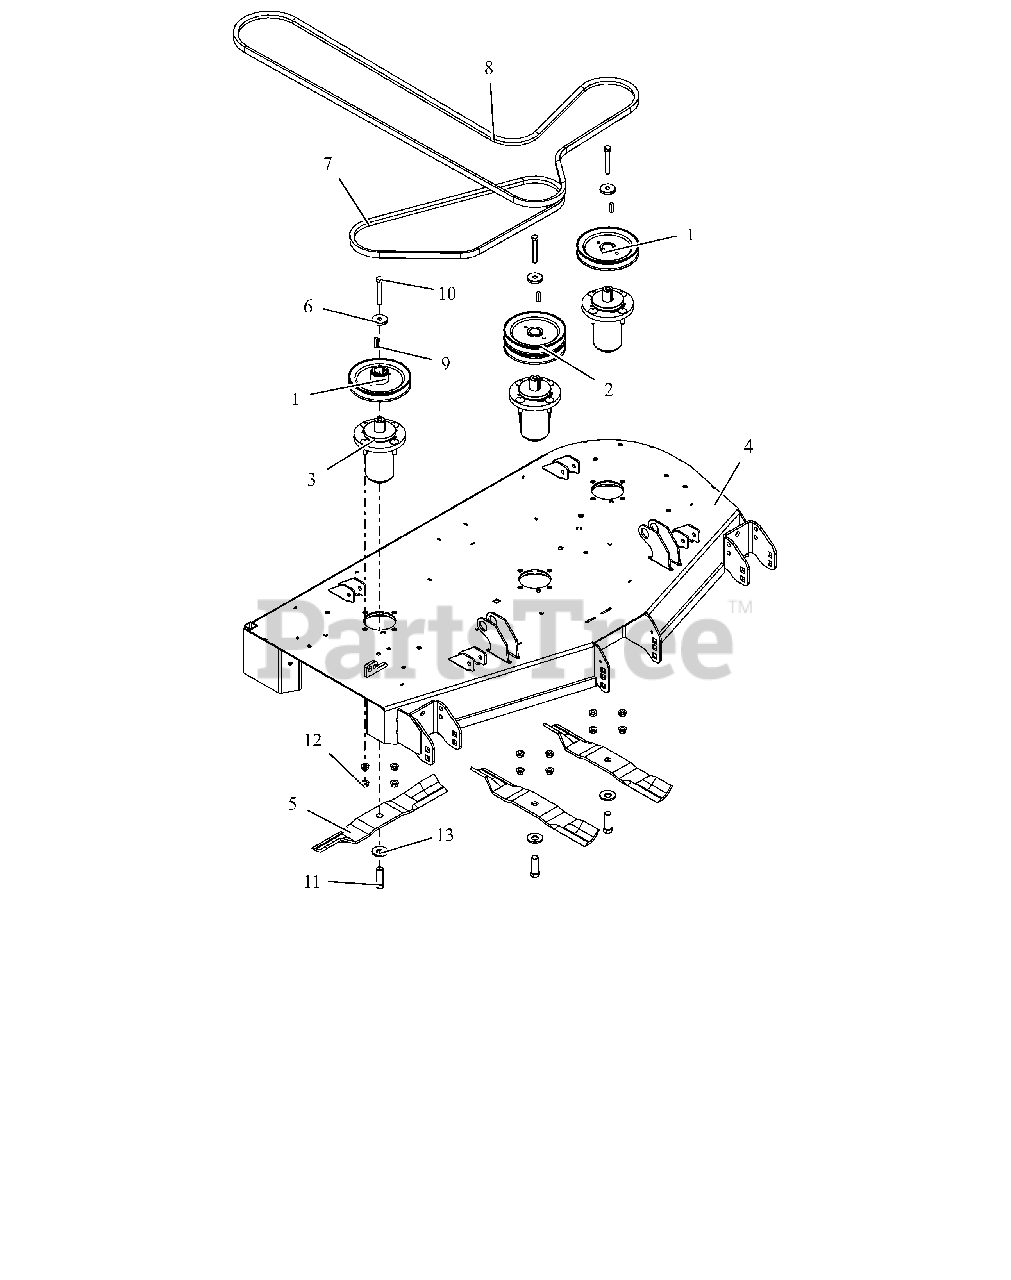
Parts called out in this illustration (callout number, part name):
1	PULLEY, SINGLE-1"ID X 6" OD
2	PULLEY, DOUBLE
3	ASM, MAINT FREE ALUM SPINDLE
4	KIT,DECK-48" W/DECALS-GRAVELY
5	BLADE, 16.19" MOWER (HI-LIFT)
6	RETAINER, SHEAVE
7	V-BELT, B-COGGED
8	V-BELT, HB SECTION
9	KEY, SQ .25X.25X1.00 RC 40-50
10	BLT, HEX .38-16X2.75 G8 ZCC
11	BLT, HEX .62-18X1.75 G8 ZCC
12	NUT-LK-CTR-FLG .375-16 GF ZCC
13	WSHR-BLVL .669X1.535X.138
